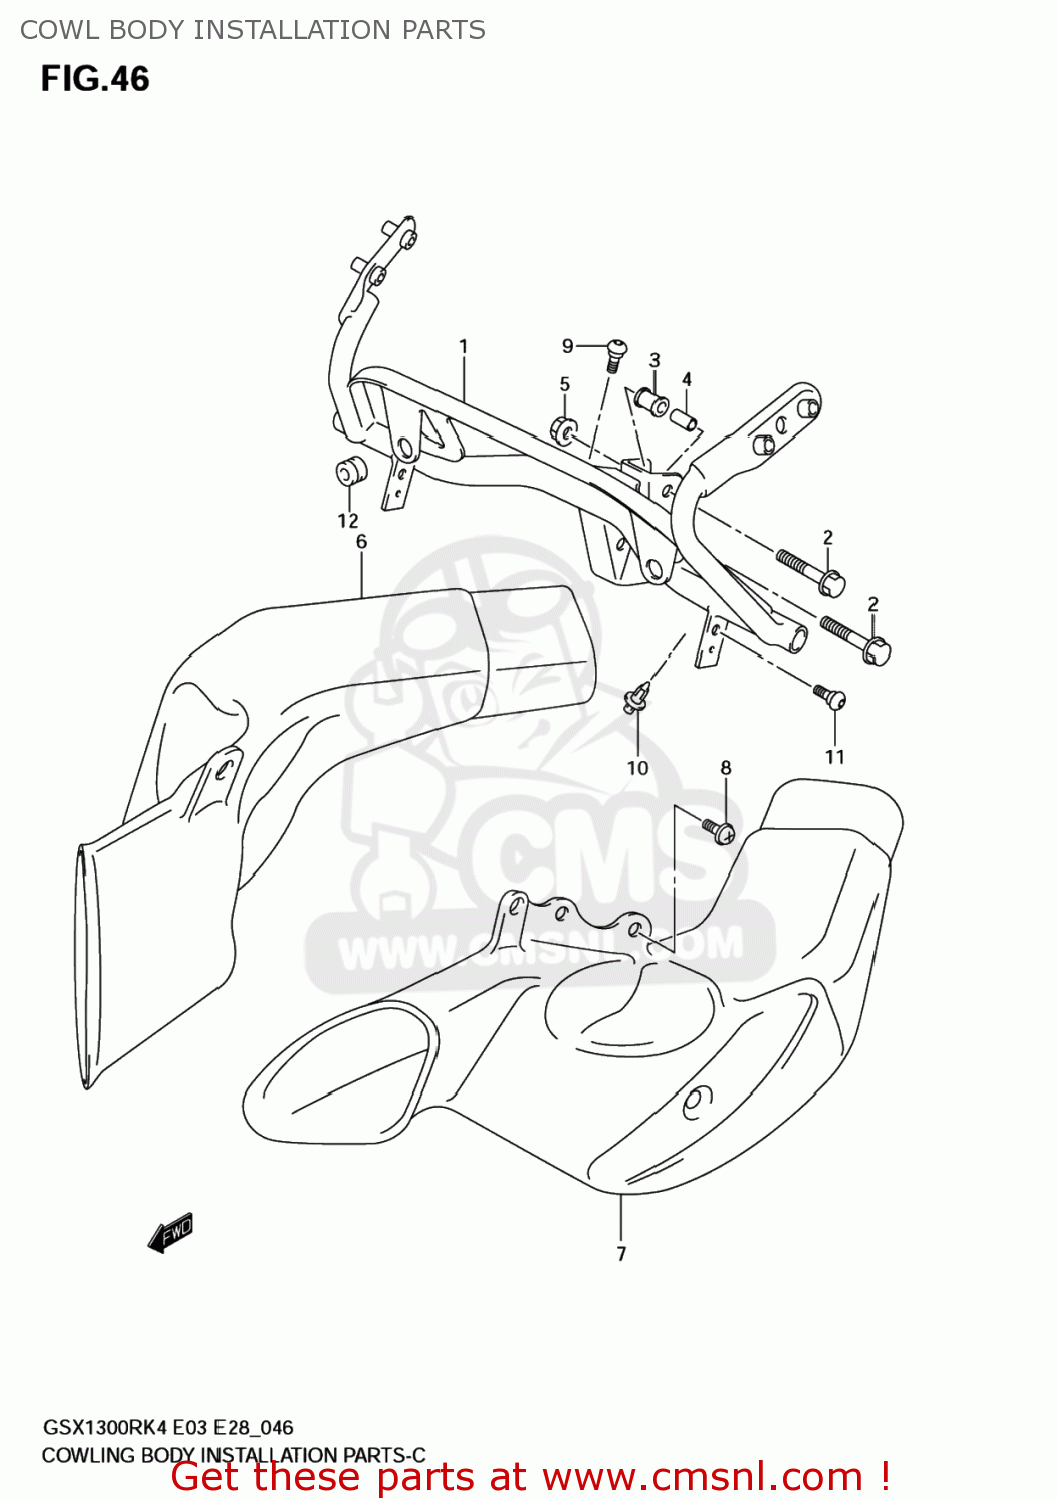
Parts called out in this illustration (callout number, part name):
1	BRACE,COWLING
2	BOLT
3	CUSHION,COWLING BRACE
4	SPACER(8.6X12.2X26.5)
5	NUT
6	PIPE,AIR INTAKE,R
7	PIPE,AIR INTAKE,L
8	SCREW(5X16)
9	SCREW(5X16)
10	CLIP(BLACK)
11	SCREW(5X16)
12	CUSHION
